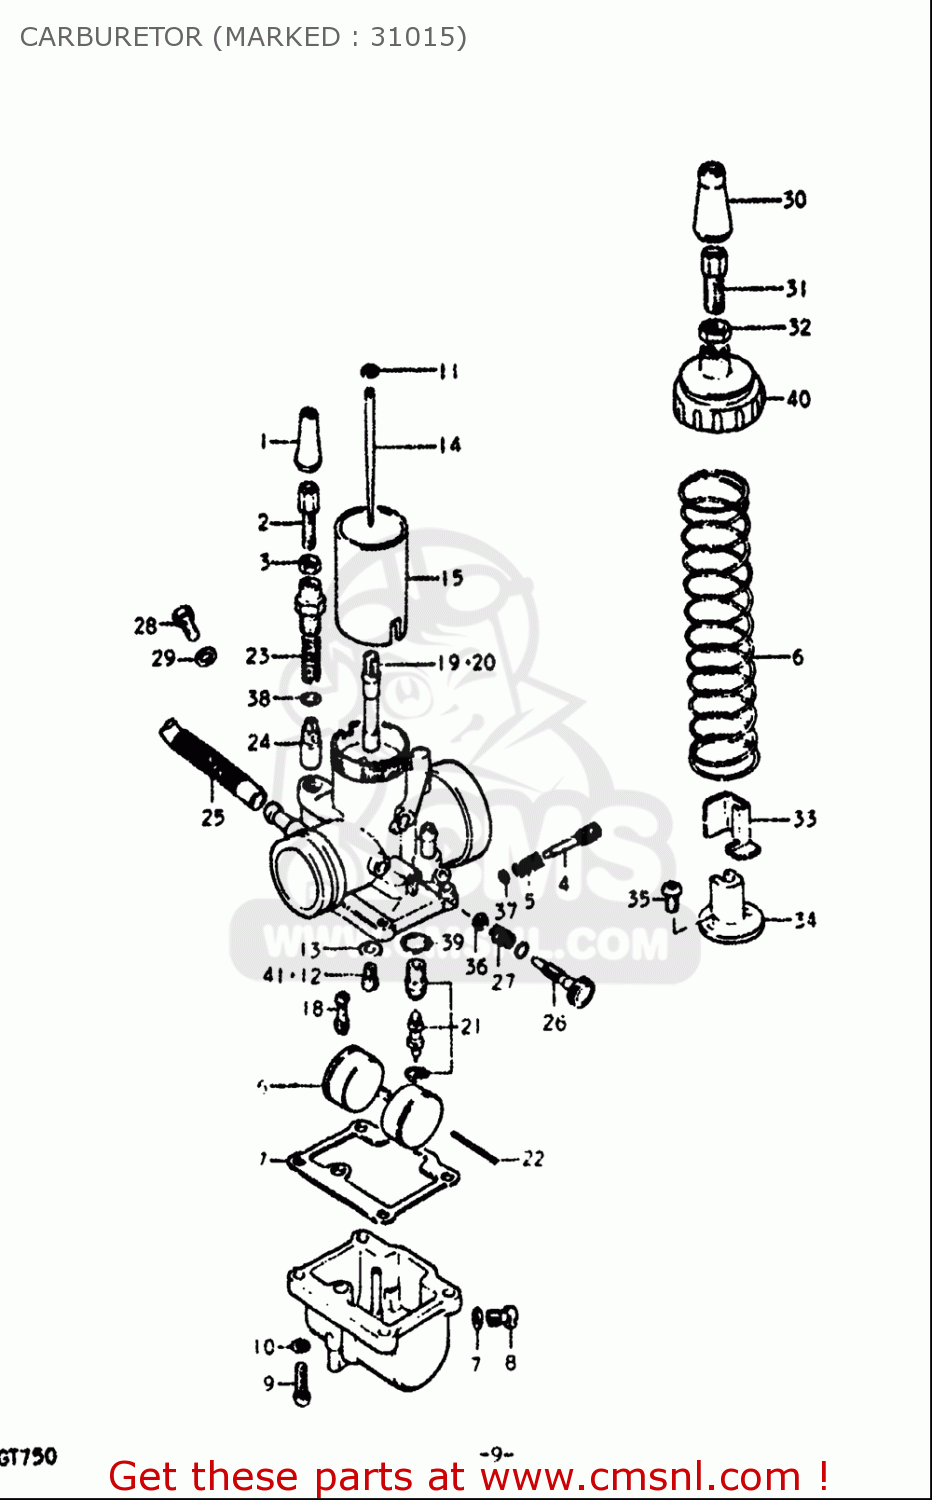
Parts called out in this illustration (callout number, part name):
1	CAP
2	ADJUSTER,CABLE
3	NUT
4	SCREW,PILOT AIR
5	SPRING
7	GASKET,DRAIN,PLUG (NAS)
8	PLUG
9	SCREW 4X16
10	WASHER,LOCK
11	CLIP
12	JET,MAIN
13	WASHER
16	FLOAT
17	GASKET,FLOAT CAHMBER (NAS)
18	JET,PILOT(30)
21	VALVE ASSY,NEEDLE
22	PIN,FLOAT
23	SPRING
24	PLUNGER,STARTER
27	SPRING,THROTTLE SCREW
28	BOLT
29	GASKET,THRO VALVE INSPECTION (NAS)
30	CAP
31	ADJUSTER,CABLE
32	NUT
34	CONNECTOR
35	SCREW
36	COVER
37	O RING
39	GASKET,MAIN JET HOLDER (NAS)
41	JET,MAIN(105)
